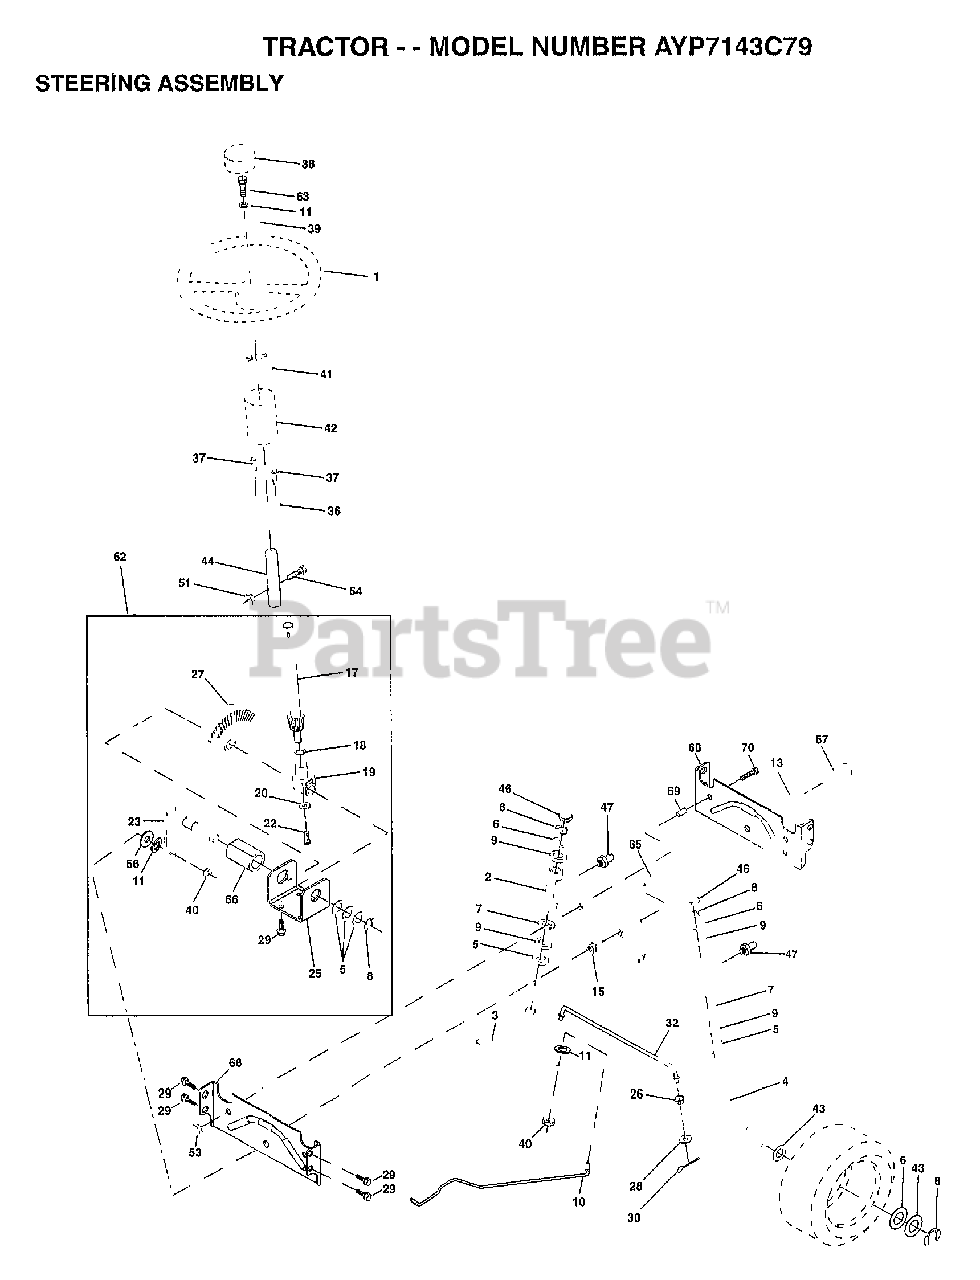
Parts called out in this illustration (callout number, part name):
1	WHEEL STR AYP BLK
2	AXLE ASM
3	SPINDLE.ASM.LH
4	"SPINDLE ASM,RH"
5	WASHER .T
6	WASHER
7	WASHER
8	RING
9	COL. SRTG. BEAR.
10	DRAGLINK-STAMPED
11	LOCKWASHER
13	BEARING AXLE
15	"NUT-LOC,FLANGE LT"
17	SHAFT ASM STEERIN
18	THRUST WASHER
19	SUPPORT.SHAFT
22	SCREW HEX SOC1/4-
25	BRKT-STEERING
26	BUSHING.DRAGLINK
27	GEAR SECTOR
28	WASHER
29	SCREW
30	COTTER PIN
32	TIE ROD
36	BUSHING.STEERING
37	"SCREW-TT,10-32 FL"
38	CAP STEER AYP
39	WASHER T
40	GRIPCO NUT
41	ADAPTER LT
42	BOOT.STEER.PL
43	WASHER
44	EXT SHAFT STEERIN
46	CAP
47	ZERK M
51	NUT
54	BOLT
62	KIT STEERING ASM
63	BOLT
65	SPACER AXLE
66	"BEARING-ARM,PITMA"
67	BOLT
68	BRACE AXLE
69	"SPACER BRCAE,AXLE"
70	BOLT.HEX.3/8-16X2
